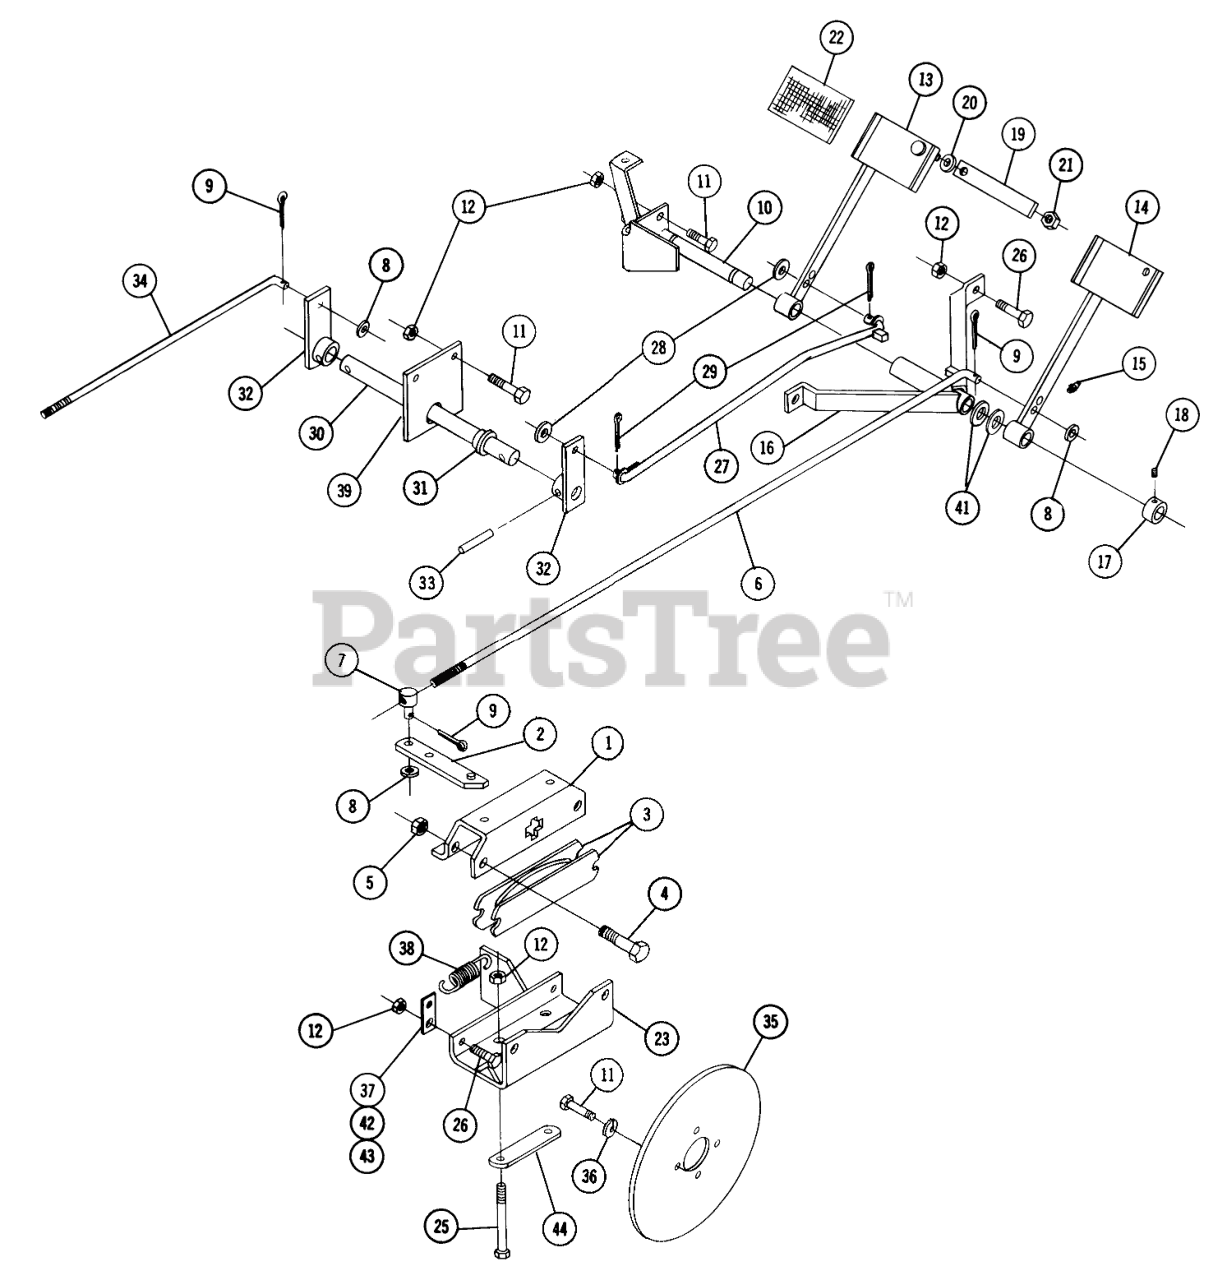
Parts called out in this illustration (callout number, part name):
1	Secondary Bracket
2	Lever Assembly
3	PLATE-ASSY- STATOR
4	Bolt-Shoulder 1/2 x 1 1/2
5	Retaining Ring
6	Rod Assembly
7	Trunnion
8	Washer
9	Cotter Pin
10	Pedal Pivot Assembly
11	BOLT
12	NUT
13	Pedal-L.H.
14	Pedal-R.H.
15	Fitting-Grease
16	Brace Assembly
17	Collar
20	Washer
21	NUT
22	Brake Pedal Pad
23	Plate-Brake Mounting RH
25	HHCS
26	Bolt
27	Rod Assembly
28	Washer
29	Cotter Pin
30	Shaft
31	BUSHING
32	Arm Assembly
33	SPIROL ROLL PIN
34	Rod Assembly
36	LOCKWASHER
37	Plate-Spring Anchor
38	SPRING
39	Support Bracket
41	Washer
42	PLATE SPRING ANCHOR
43	Spring Tab
44	BRACKET-REAR LINK MOUNTING
